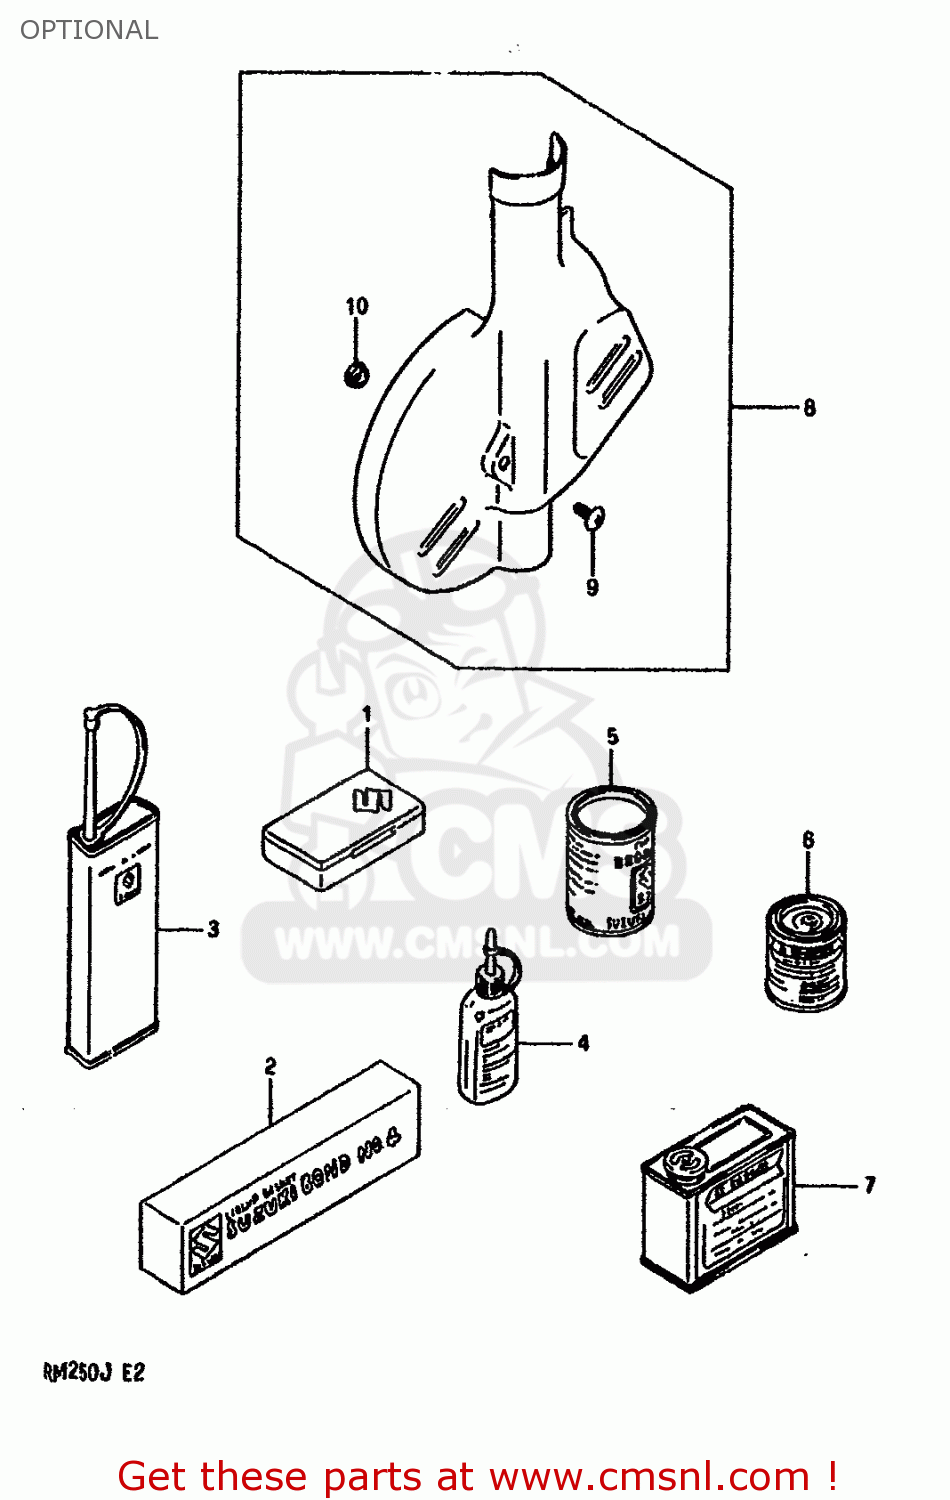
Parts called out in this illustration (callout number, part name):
1	TUBE REPARING TOOL
2	BOND 1104
3	THREAD LOCK NO.1401 CLEAR 200G
4	THREAD LOCK NO
5	GREASE(C)EP2 LITHIUM 150G
6	PAINT (ACCENT BLUE)
7	PAINT (ACCENT BLUE)
8	COVER,FRONT DISC
9	SCREW(8X12)
10	WASHER
